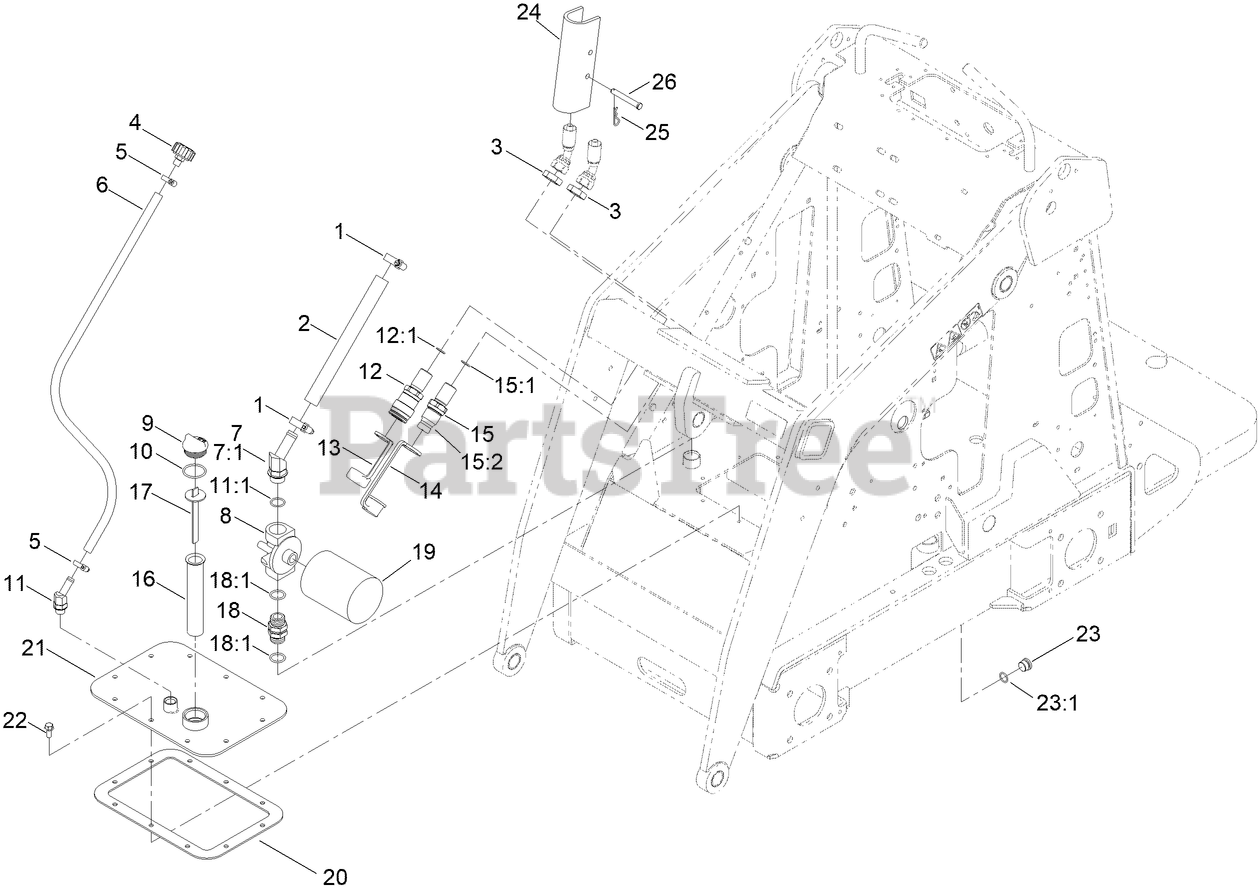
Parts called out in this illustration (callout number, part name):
1	CLAMP-HOSE
2	HOSE-HYD, SUCTION, HI
3	NUT-LOCK, BULKHEAD
4	BREATHER
5	CLAMP-HOSE
6	HOSE-VENT
7	FITTING-ELBOW45
7:1	O-RING
8	HEAD-FILTER
9	PLUG-PLASTIC
10	O-RING
11	FITTING-ELBOW, 45
11:1	O-RING
12	BULKHEAD COUPLER ASM
12:1	O-RING
13	CAP-DUST, COUPLER
14	CAP-DUST, NIPPLE
15	BULKHEAD NIPPLE ASM
15:1	O-RING
16	FILTER-SCREEN
17	DIPSTICK-OIL
18	FITTING-THREAD, STRAIGHT
18:1	O-RING
19	FILTER-OIL, TRANSMISSION
20	GASKET-COVER
22	SCREW-HHF
23	PLUG-HEX
23:1	O-RING
24	LOCK-CYLINDER
25	PIN-HAIR
26	PIN-CLEVIS
